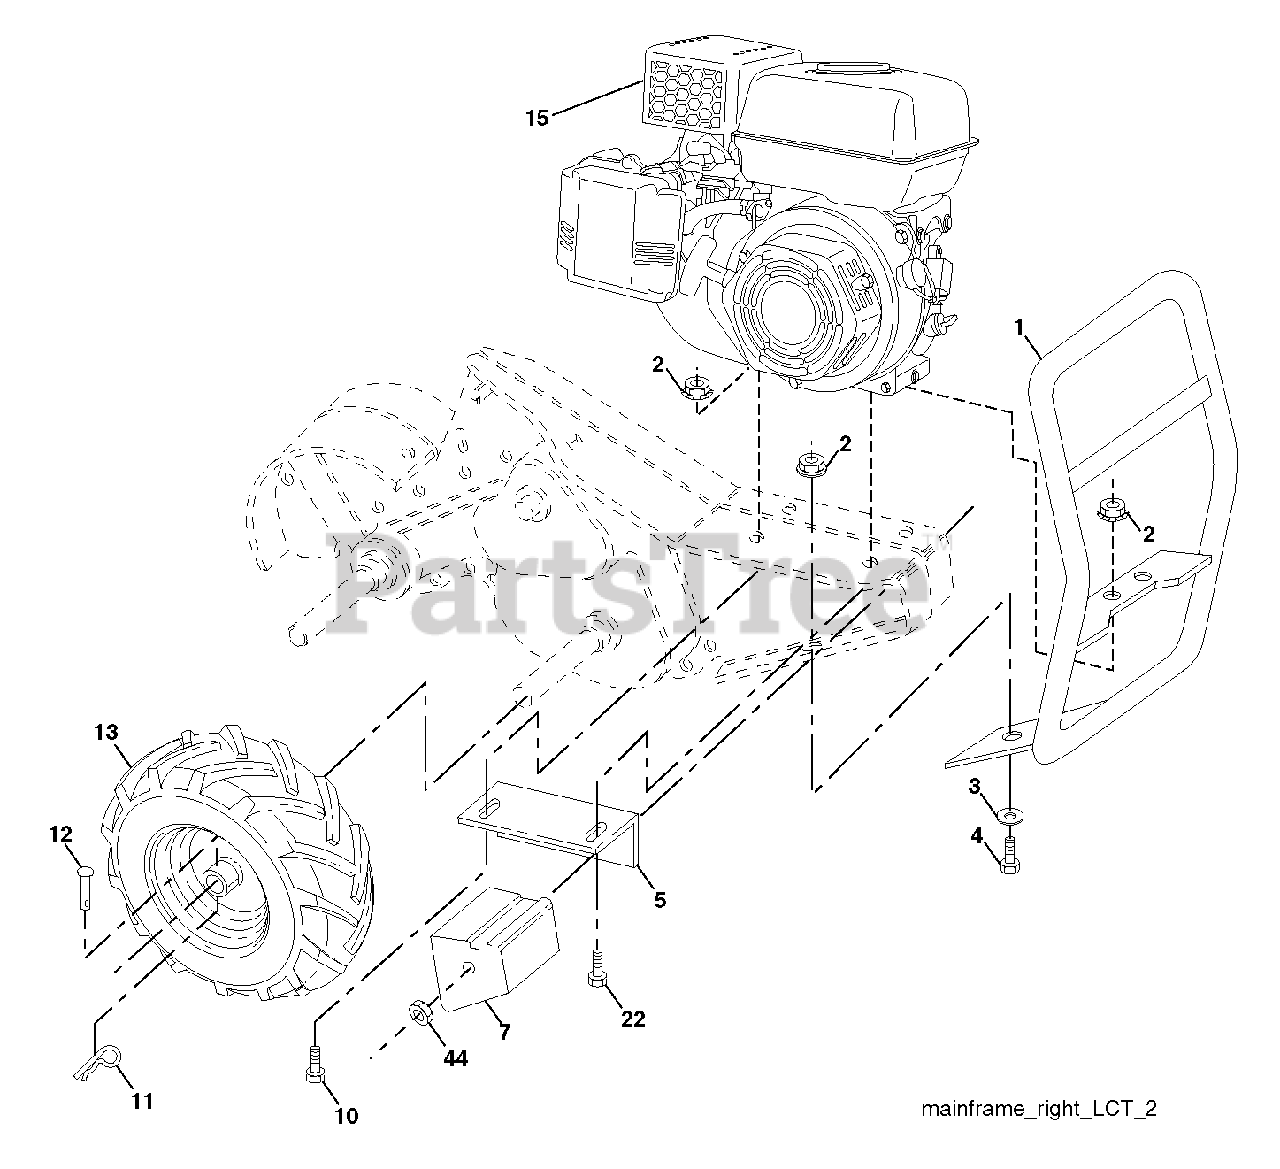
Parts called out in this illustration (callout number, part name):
1	BUMPER.ASM.TILLER.BLACK
2	LOCKNUT-FLANGE 5/16-18
3	WASHER
4	BOLT
5	BRACKET.REINFORCEMENT.RH.BLACK
7	COUNTERWEIGHT.RH
10	BOLT
13	WHEEL ASM.16 X 4 X 8.DR.RH.421
15	ENGINE.LCT.208CC.FT TILLER
22	BOLT
